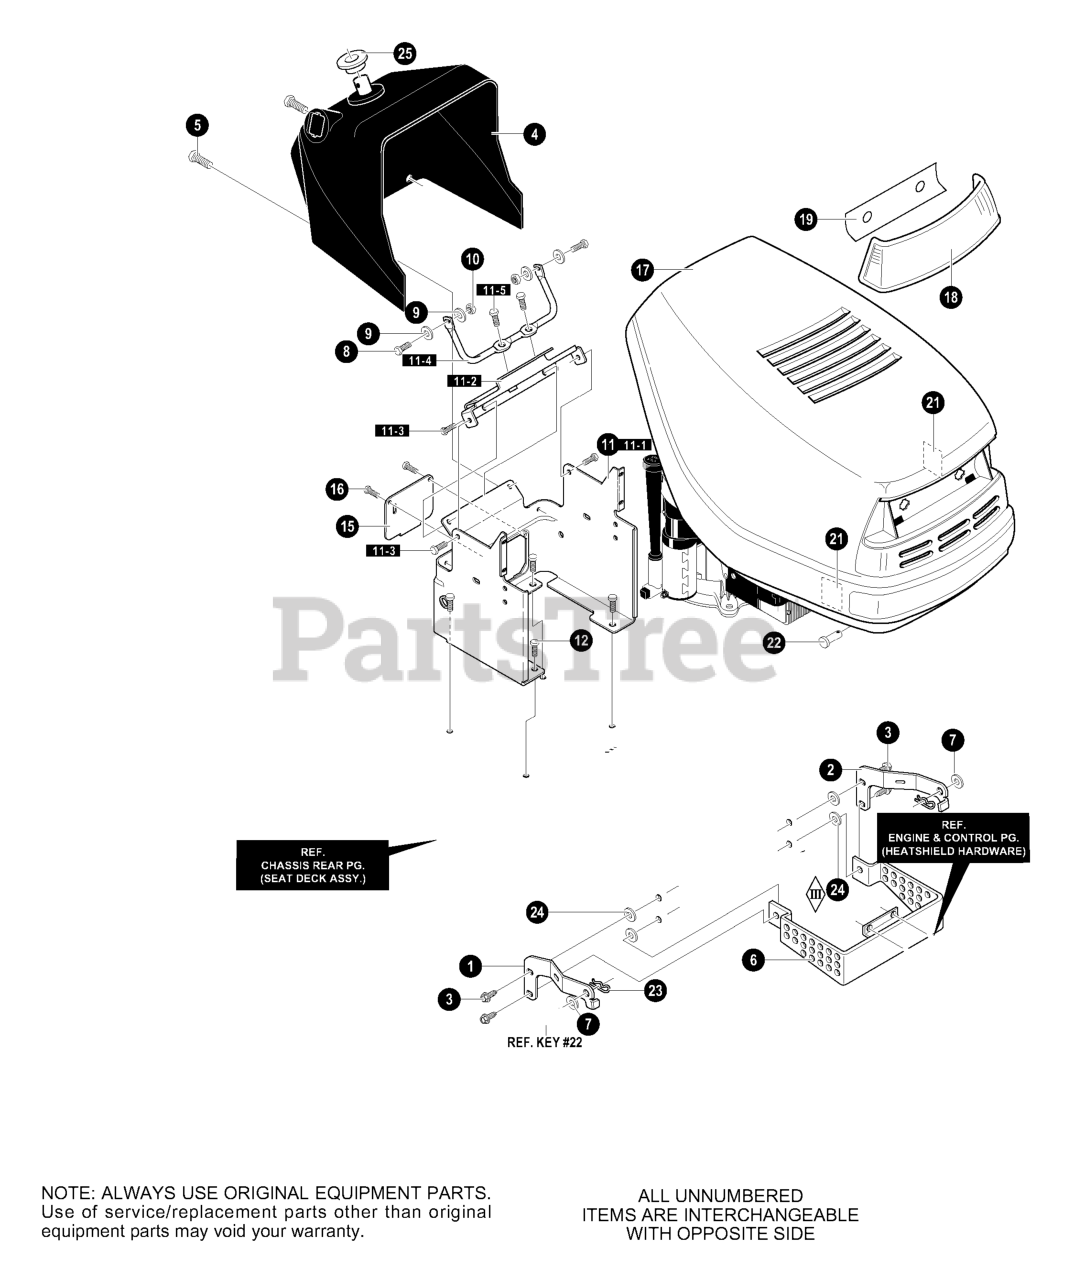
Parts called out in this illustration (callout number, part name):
1	BRACKET, HOOD RH
2	BRACKET, HOOD LH
3	SCREW, 5/16-18 x 0.75
4	DASH
5	SCREW,1/4-14X.75
6	HEAT SHIELD GUARD
7	WASHER, FLAT .375X.87 INSULATE
8	SCREW, 1/4-20X .75 HHC
9	WASHER, FLAT .286X .63X.065
10	NUT, 1/4-20 REGHEXCTRLK
11	ASSEMBLY LOWER CONSOLE
11-1	TOWER, LOWER DASH
11-2	SUPPORT, STEERING
11-3	SCREW, 1/4-20X .50
11-4	ROD, DASH BRACE
11-5	SCREW, 1/4-20X .50
12	SCREW, 5/16-18 x 0.75
15	PANEL, ACCESS
16	SCREW, 10-24X.5
18	LENS, HEADLAMP
19	FOIL, LENS
21	FOIL, HEAT REFLECTOR
22	PIN,CLEVIS
23	PIN,HAIR
24	WASHER, PLASTIC .315X.75X.064
25	BUSHING, STEERING SHAFT
